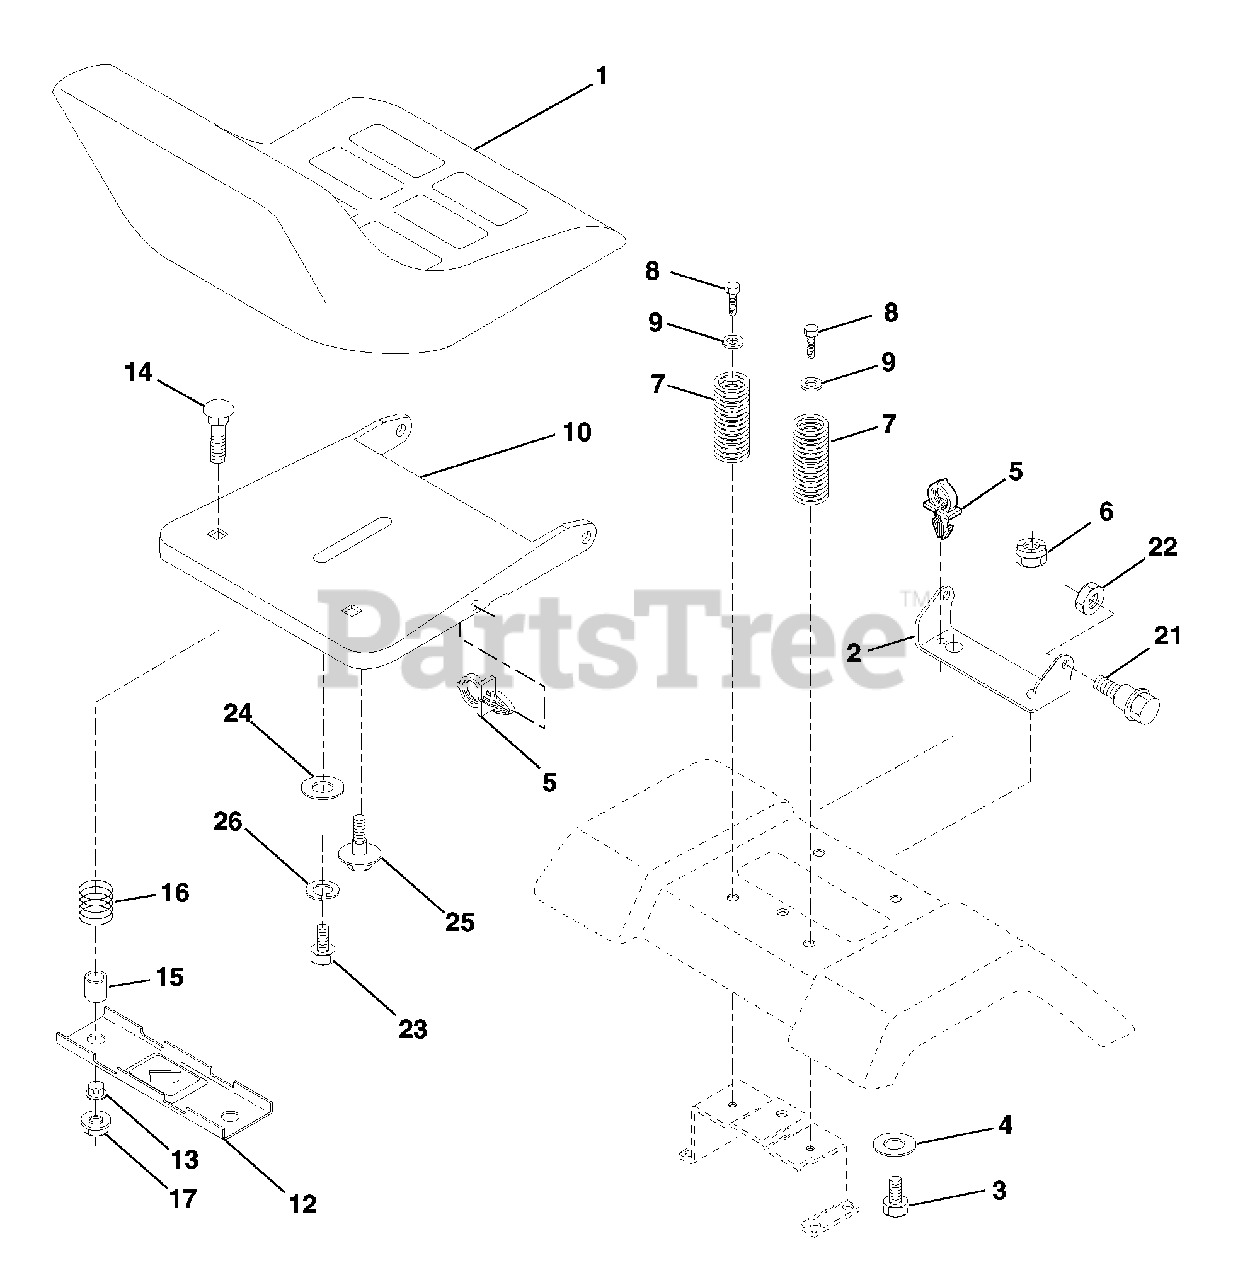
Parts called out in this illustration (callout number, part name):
1	Seat
2	Bracket Pivot Seat 8 720
3	Bolt Fin Hex 3/8-16unc X 1
4	Washer 13/32 X 1 X 10 Ga
5	Clip Push-In
6	Nut Hex w/Ins. 3/8-16 Unc
7	Spring Seat Cprsn 2 250 Blk Zi
8	Screw Thdrol 3/8-16 X 1 Ty-tt
9	Washer 13/32 X 1 X 14 Ga.
10	Pan Seat
12	Bracket Mounting Switch
13	Bushing Snap Blk Nyl 50 Id
14	Bolt Rdhd Sqnk 1/4-20x1-1/2
15	Spacer Split 28x 96 Yel Zinc
16	Spring Cprsn 1 27 Blk Pnt
17	Nut Lock 1/4 Lge Flg Gr 5 Zinc
21	Bolt Shoulder 5/16-18 Unc
22	Nut Hex Lock W/Ins 5/16-18
23	Bolt, Hex Head, Fin 1/2-13 x 7/8 Grade 5
24	Washer 17/32 X 1-3/16 X 12 Ga.
25	Bolt Shoulder 5/16-18 X 62
26	Washer Lock
